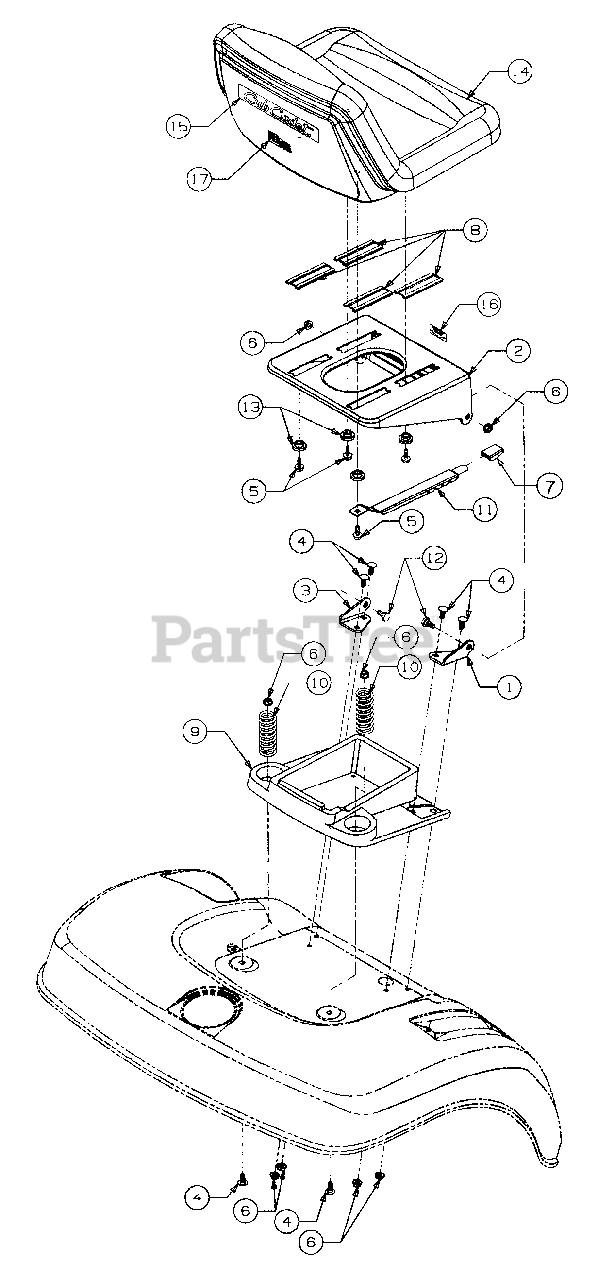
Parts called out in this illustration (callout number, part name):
5	Screw, Hx Wsh Hd Tap 5/16-18x.75
6	Nut, Hex Flange Lock, 5/16-18
7	Knob, Seat Adjuster
8	Slide, Seat
9	Tray, Tool
10	Spring, Comp, 1.9 OD x 2.4
11	Adjuster, Seat
12	Bolt, Shoulder
13	Spacer, Shoulder
14	Seat, High Back
15	Graphic, Seat Back
16	Graphic, Seat Adjuster
17	Graphic, Made in USA
